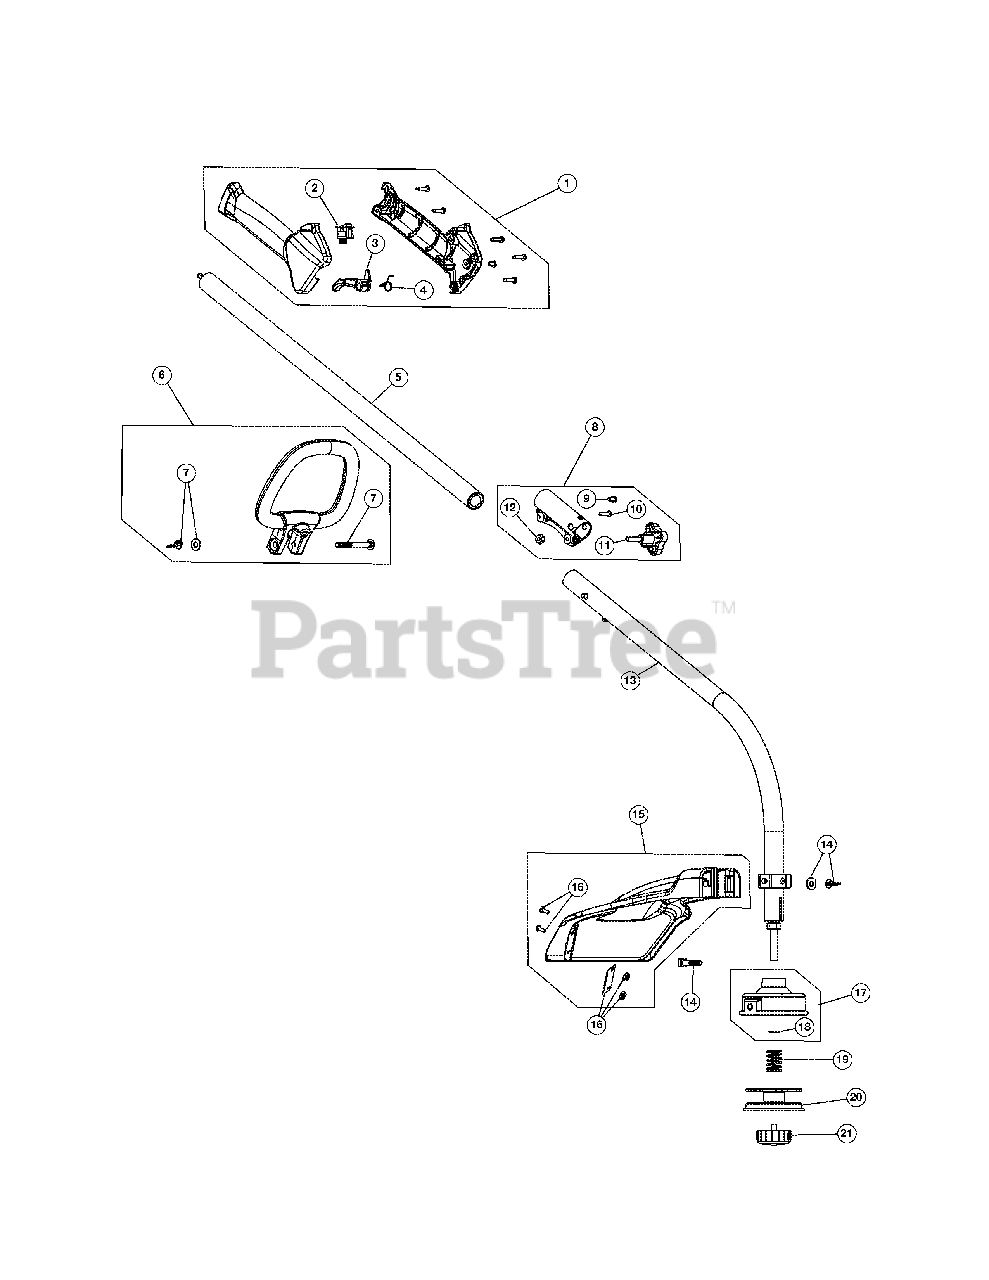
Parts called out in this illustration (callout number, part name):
1	Throttle Housing Assembly (Incl Ref No. 2-4)
3	Throttle Trigger
4	Throttle Trigger Spring
5	Upper Shaft Housing Assembly
6	D-Handle (Incl Ref No. 7)
7	D-Handle Hardware Assembly
8	Split Boom Coupler (Incl Ref No. 9-12)
9	Anti-Rotation Screw
11	Adjustment Knob
12	Knob Retainer Nut
13	Lower Shaft Housing Assembly
14	Shield Mounting Hardware
15	Shield Assembly (Incl Ref No. 16)
16	Blade Assembly
17	Outer Spool Assembly (Incl Ref No. 18)
18	Retainer
20	Inner Reel
21	Bump Head Knob Assembly
